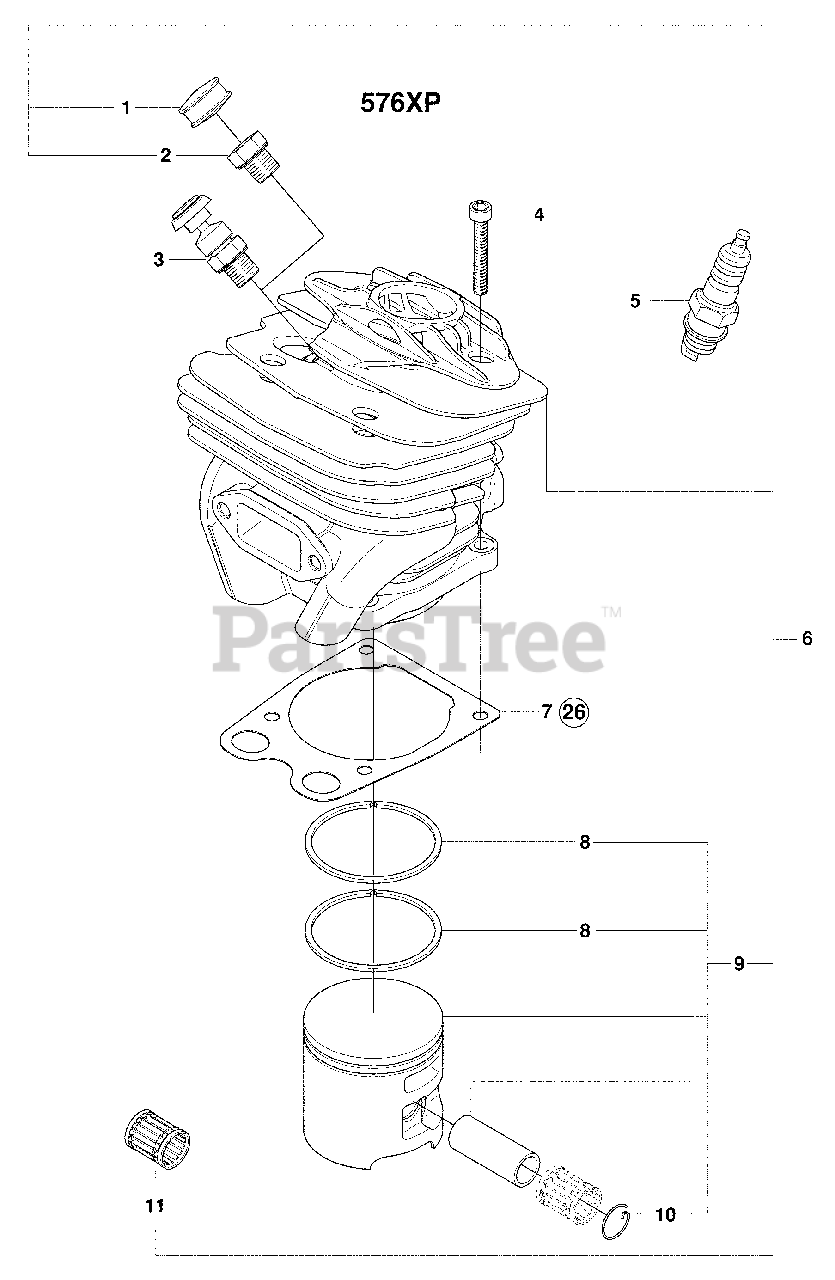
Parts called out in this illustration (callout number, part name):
2	Cylinder Plug
3	Valve
4	Screw, MC6S 5 X 25
5	Solid Spark Plug, BPMR7A
6	Cylinder Assembly
8	Piston Ring
9	Piston Assembly
11	Needle Bearing Piston Pin, 12 X 1
26	Gasket Kit
